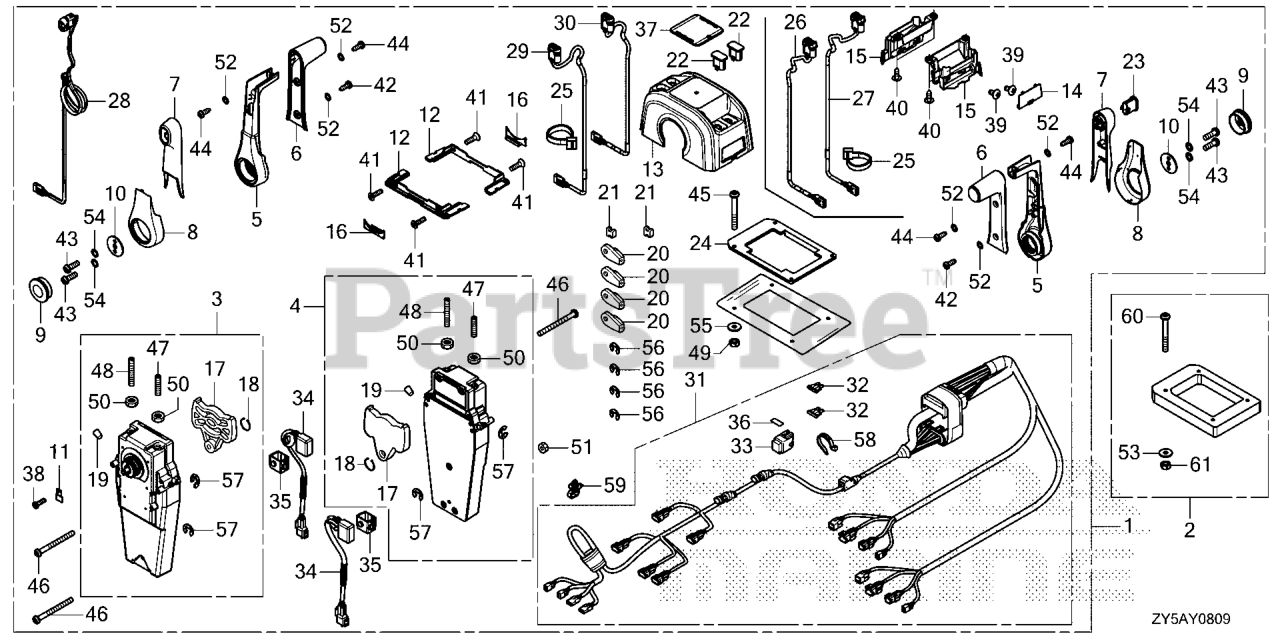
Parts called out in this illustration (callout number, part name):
1	BOX KIT, REMOTE CONTROL (TOP MOUNT DUAL) (TROLLING CONTROL)
1	BOX KIT, R/C
1	BOX KIT
2	SPACER KIT, REMOTE CONTROL BOX (TOP MOUNT DUAL)
3	HOUSING ASSY., L. (INNER) (TOP MOUNT) (NOT AVAILABLE)
4	HOUSING ASSY., R. (INNER) (TOP MOUNT) (NOT AVAILABLE)
5	HANDLE, REMOTE CONTROL (NOT AVAILABLE)
6	COVER, GRIP
7	GRIP
8	COVER, LEVER (NOT AVAILABLE)
9	BUTTON, THROTTLE (NOT AVAILABLE)
10	PLATE, HANDLE
11	PLATE, CABLE CLAMP
12	BRACKET, REMOTE CONTROL HOUSING (NOT AVAILABLE)
13	HOUSING, DUAL REMOTE CONTROL BOX (NOT AVAILABLE)
14	PLUG, DUAL HOUSING (NOT AVAILABLE)
15	GUIDE, DUAL WATER (NOT AVAILABLE)
16	HOUSING, LEAD (NOT AVAILABLE)
17	PLATE, DWELL
18	RING, SNAP (NOT AVAILABLE)
19	GROMMET (NOT AVAILABLE)
20	TERMINAL, CABLE
21	SPACER, CABLE CLAMP
22	CAP, BLANK (NOT AVAILABLE)
23	CAP, POWER TRIM-TILT BLANK (NOT AVAILABLE)
24	GASKET, DUAL (LOOSE PARTS) (NOT AVAILABLE)
25	BAND, TY-RAP (POWER TRIM-TILT) (NOT AVAILABLE)
26	SWITCH ASSY., TROLLING CONTROL (PORT) (NOT AVAILABLE)
27	SWITCH ASSY., TROLLING CONTROL (STAR) (NOT AVAILABLE)
28	SWITCH ASSY., POWER TRIM-TILT (NOT AVAILABLE)
29	SWITCH ASSY., POWER TRIM-TILT (PORT) (NOT AVAILABLE)
30	SWITCH ASSY., POWER TRIM-TILT (STAR) (NOT AVAILABLE)
31	CABLE ASSY., POWER TRIM-TILT (TROLLING CONTROL) (NOT AVAILABLE)
31	CABLE ASSY.
31	CABLE ASSY., POWER TRIM-TILT (NOT AVAILABLE)
32	FUSE, BLADE (3A)
33	COVER ASSY., FUSE (3A)
34	RELAY ASSY., CONTROL (NOT AVAILABLE)
35	HOLDER, RELAY (NOT AVAILABLE)
36	LABEL, FUSE (3A)
37	MARK, REMOTE CONTROL (DUAL) (NOT AVAILABLE)
38	SCREW, PAN (5X16)
39	SCREW, TRUSS (5X10) (NOT AVAILABLE)
40	SCREW, TRUSS (5X16) (TAPPING) (NOT AVAILABLE)
41	SCREW, PAN (5X18)
42	SCREW, PAN (5X14) (TAPPING) (NOT AVAILABLE)
43	SCREW, PAN (6X18)
44	SCREW, PAN (5X14) (TAPPING)
45	SCREW, PAN (5X40)
46	SCREW, PAN (5X55)
47	BOLT, STOPPER (F) (NOT AVAILABLE)
48	BOLT, STOPPER (R) (NOT AVAILABLE)
49	NUT, HEX. (5MM)
50	NUT (6MM) (LOOSE PARTS)
51	NUT, HEX. (5MM)
52	WASHER, LOCK (5MM)
53	WASHER, PLAIN (5MM)
54	WASHER, LOCK (6MM)
55	WASHER, PLAIN (5MM)
56	E-RING (6MM) (LOOSE PARTS)
57	E-RING (6MM) (LOOSE PARTS)
58	HOLDER, CONNECTOR (128.6MM) (NATURAL)
59	CLIP, HARNESS BAND (NOT AVAILABLE)
60	SCREW, PAN (5X65)
61	NUT, HEX. (5MM)
